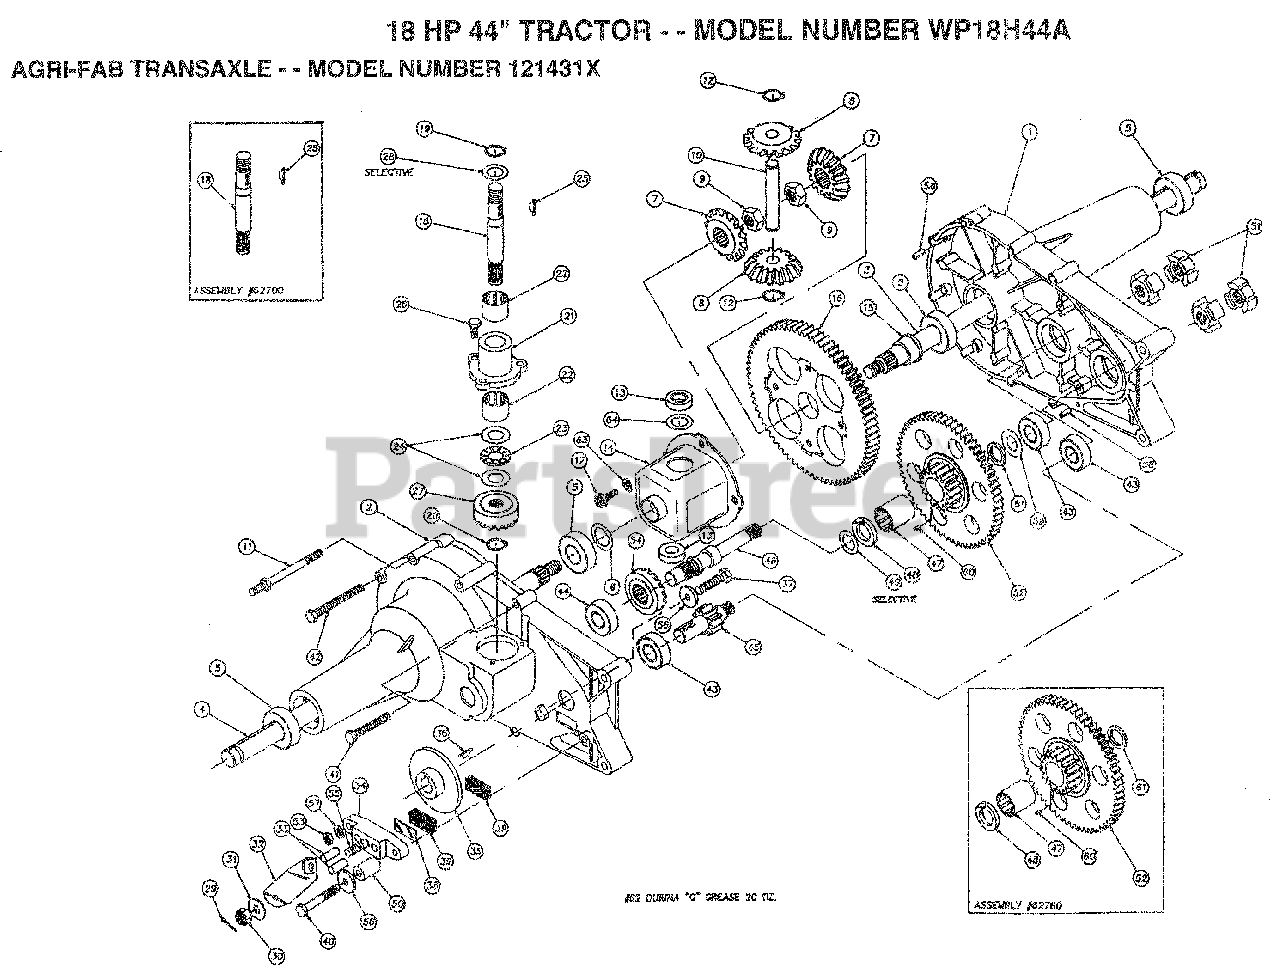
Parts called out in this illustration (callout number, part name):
1	Housing, Half L.H.
2	Housing, Half R.H.
3	Axle L.H.
4	Axle R.H,
5	Bearing, Ball
6	Washer, Flat 3/4 x 1-1/8 x .030
7	Gear, Miter
8	Gear, Miter
9	Nut, Hex Jam w/Patch 1/2-20
10	Shaft, Cross
11	Screw, Stud
12	Snap, Ring
13	Bearing, Thrust
14	Housing Assembly, Differential
15	Bearing, Flange
16	Gear, Differential 72 Tooth
17	Bolt, Torx Head 1/4-28 x 5/8"
18	Shaft, Input
19	Snap, Ring
20	Retaining Ring 7/16"
21	Housing, Input Bearing
22	Bearing, Needle
23	Bearing, Thrust
24	Washer, Flat 6/8 x 1-1/8 x ,030
25	Key, Hi-Pro 3/32 x 5/8
27	Gear, Input Pinion 17 Tooth
28	Screw, Hex W/Patch 1/4-20 x 3/4
28	Washer, Flat .62 x 1 x ,05
29	Pin, Cotter
30	Nut, Castle 5/18-24
31	Washer, Fiat .343 x .88 x .062
32	Arm, Brake Actuator
33	Pin, Brake Actuating
34	Brake, Yoke
35	Disc, Brake
37	Screw, Hex 1/4-20 x 1.50
38	Key, Hi-Pro 3/16 x 5/8"
38	Plate, Puck
39	Puck, Brake
40	Screw, Hex w/Patch 1/4-20 x 2.00
41	Screw, Hex Self-Tap 1/4-20 x 2.00
42	Screw, Hex Self-Tap 1/4-20 x 3.00
43	Bearing, Ball
44	Bearing, Bail
45	Shaft, Pinion W/11 Tooth Gear
46	Shaft, Drive
47	Bearing, Needle
48	Bronze Thrust Brg. 5/8 x 1-1/4 x 7/64
49	Washer, Fiat .62 x 1.0 x ,040
51	Coupling
52	Gear, 60 and 17 Tooth
53	Nut, Hex 1/4-20
54	Gear, Drive Pinion 17 Tooth
55	Bolt, Square Head
56	Washer 15/16 x.265 x . 125
57	Washer, Spring Lock 1/4"
58	Pin, Roll 3/16" x 1/2"
59	Washer, Flat .62 x 1,0 x .030
62	Shell, Durina-O Grease (20 oz.)
63	Washer, Head Spring Lock 1/4"
64	Washer, Fiat .50 x 1.0 x .020
65	Assembly, Gear, Reduction
80	Pin, Dowel 3/32 x 1/4
81	Seal, Grease
86	Assembly, Shaft, Input
